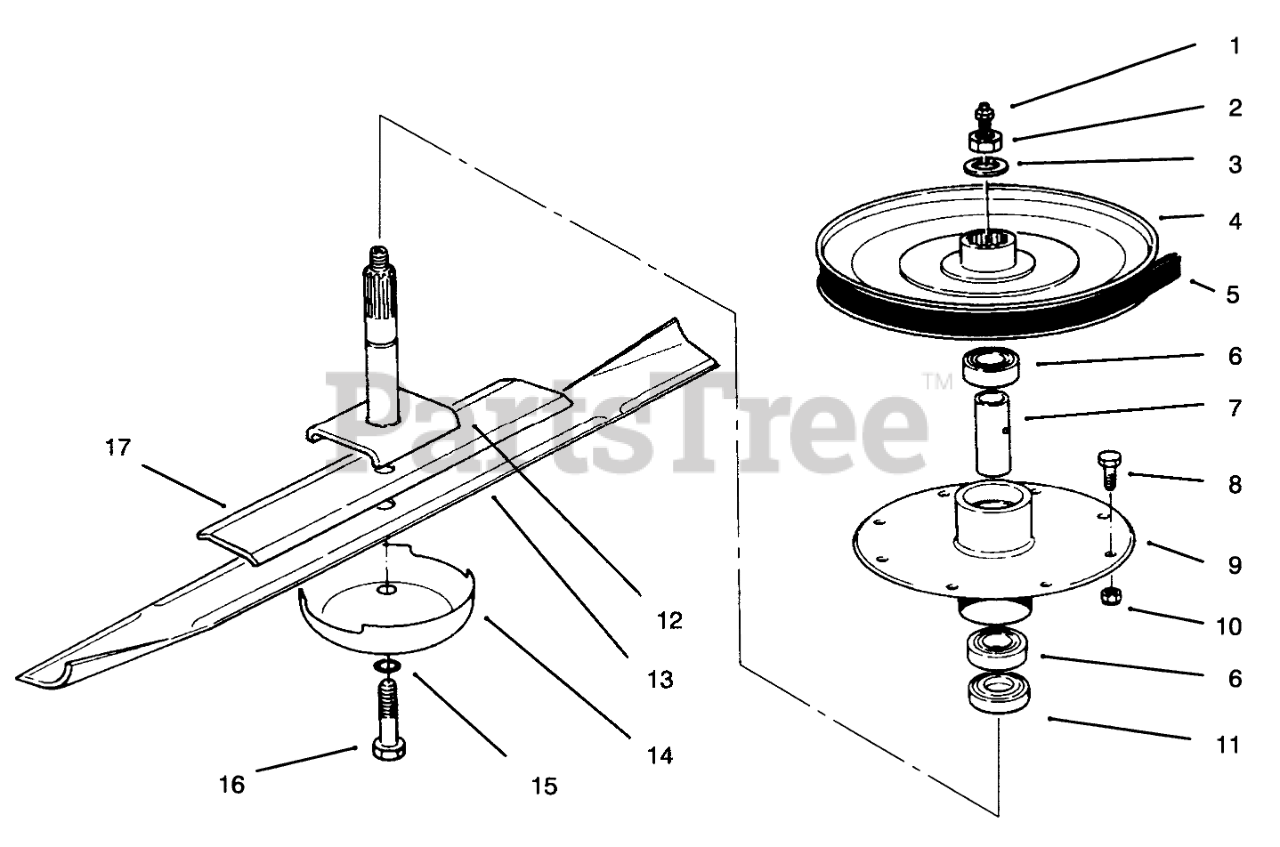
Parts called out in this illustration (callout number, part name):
1	FITTING-GREASE
2	NUT-HEX
3	WASHER
4	PULLEY ASM
5	V-BELT
6	BEARING-BALL
7	SPACER-BEARING
8	SCREW-HH
9	HOUSING-SPINDLE
10	NUT-LOCK, NI
11	SPACER
12	SHAFT-SPINDLE
13	BLADE-RECYCLER
14	Cup
15	WASHER-LOCK/SP
16	SCREW-BLADE
17	BLADE SPACER ASSEMBLY
